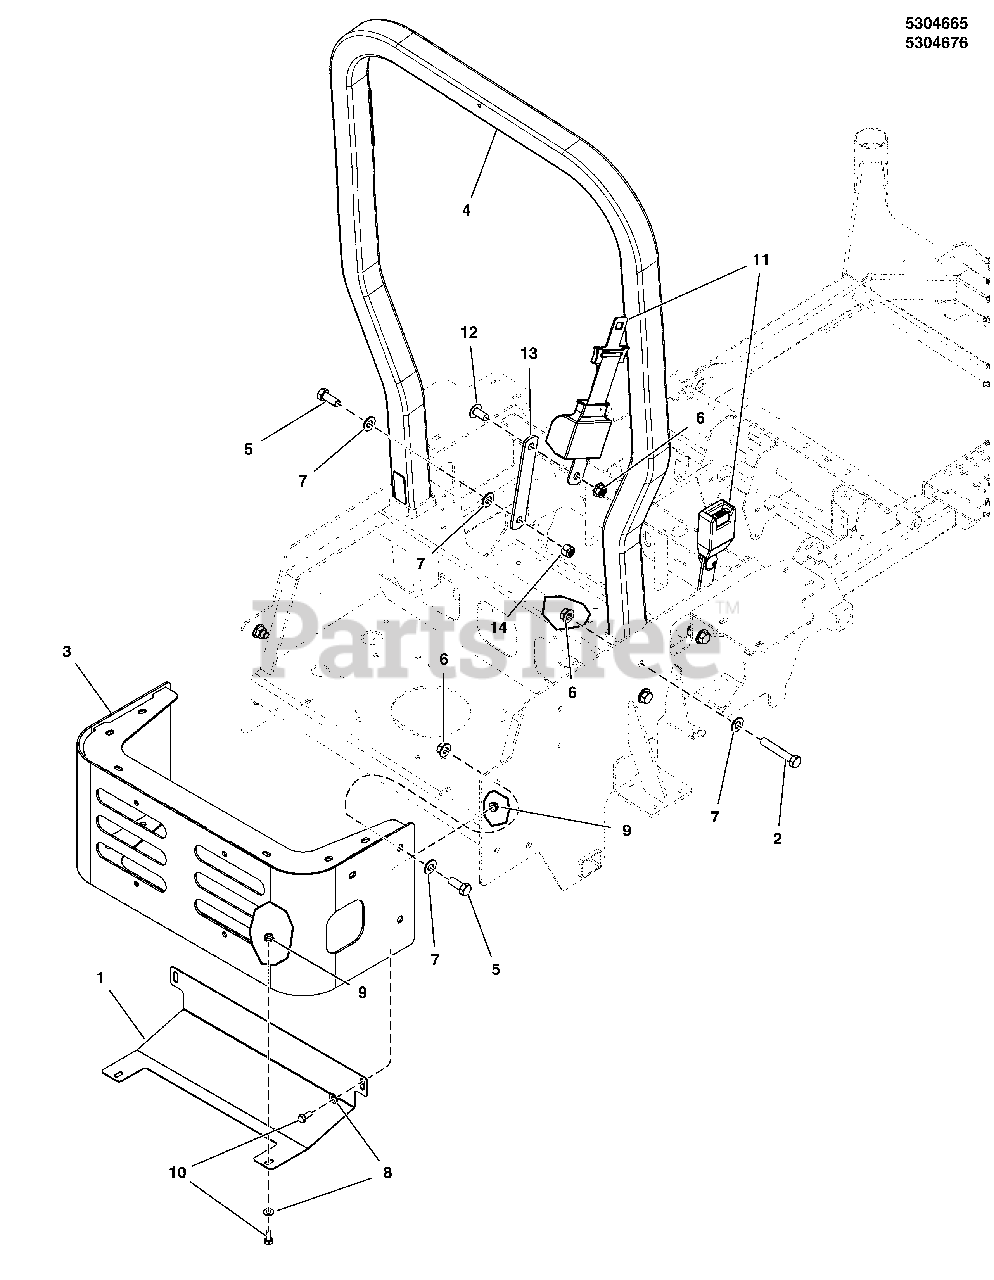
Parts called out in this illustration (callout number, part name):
1	PLATE, HEAT SHIELD, S125XT - BLACK
2	BOLT, 1/2-13 X 3 GD5 YZ
3	WELD, TALL BUMPER, 560Z - ORG
4	ROPS (Call 1-800-933-6175 x708 if replacing a ROPS)
5	BOLT, 1/2-13 X 1-1/4 GD5 YZ
6	NUT, Hex Flange, 1/2-13
7	WASHER, 1/2
8	WASHER, Flat, 5/16
9	NUT, 5/16-18, Flange Nylock, GR F, Zinc/Clear
10	CAPSCREW, Hex Head, 5/16-18 x 3/4
11	SEAT BELT ASSEMBLY, Standard
12	SCREW, 1/2 - 13 X 1.00 SCHS
13	BAR, MOUNT, SEAT BELT, IS700Z - BLK
14	NUT, 1/2-13 HEX NYLON LOCK
